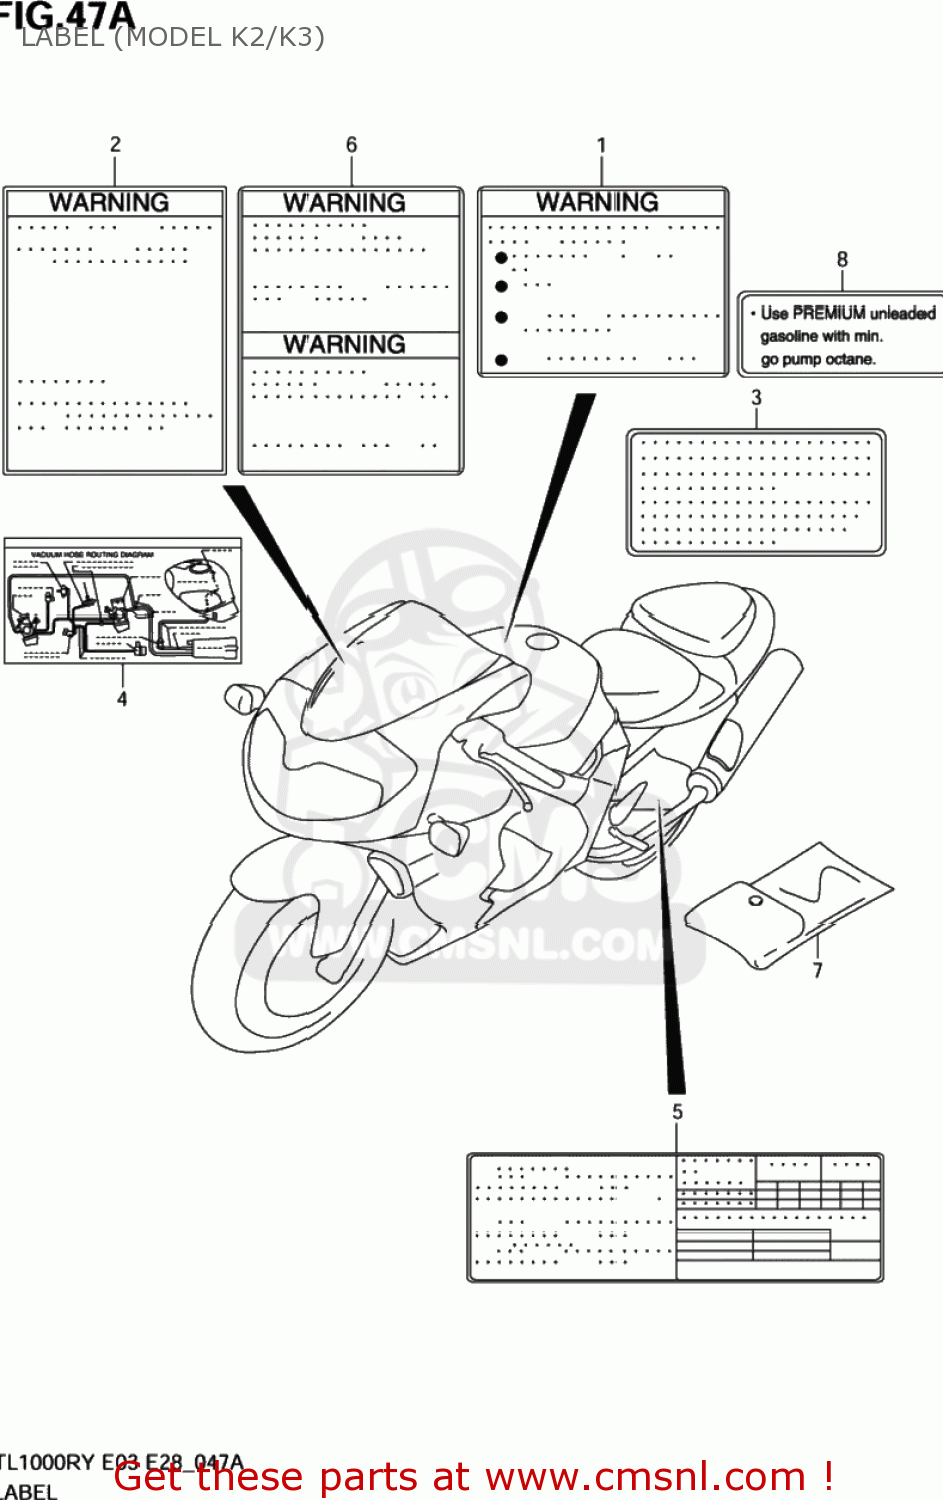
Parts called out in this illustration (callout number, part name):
1	LABEL,GENERAL WARNING
2	LABEL,SCREEN
3	LABEL,MANUAL NOTICE
4	LABEL,VACUUM HOSE ROUTING
5	LABEL,TIRE INFORMATION
6	LABEL,WARNING STEERING
7	BAG COMP,OWNERS MANUAL
8	LABEL,FUEL INFORMATION
9	MANUAL,OWNER'S
